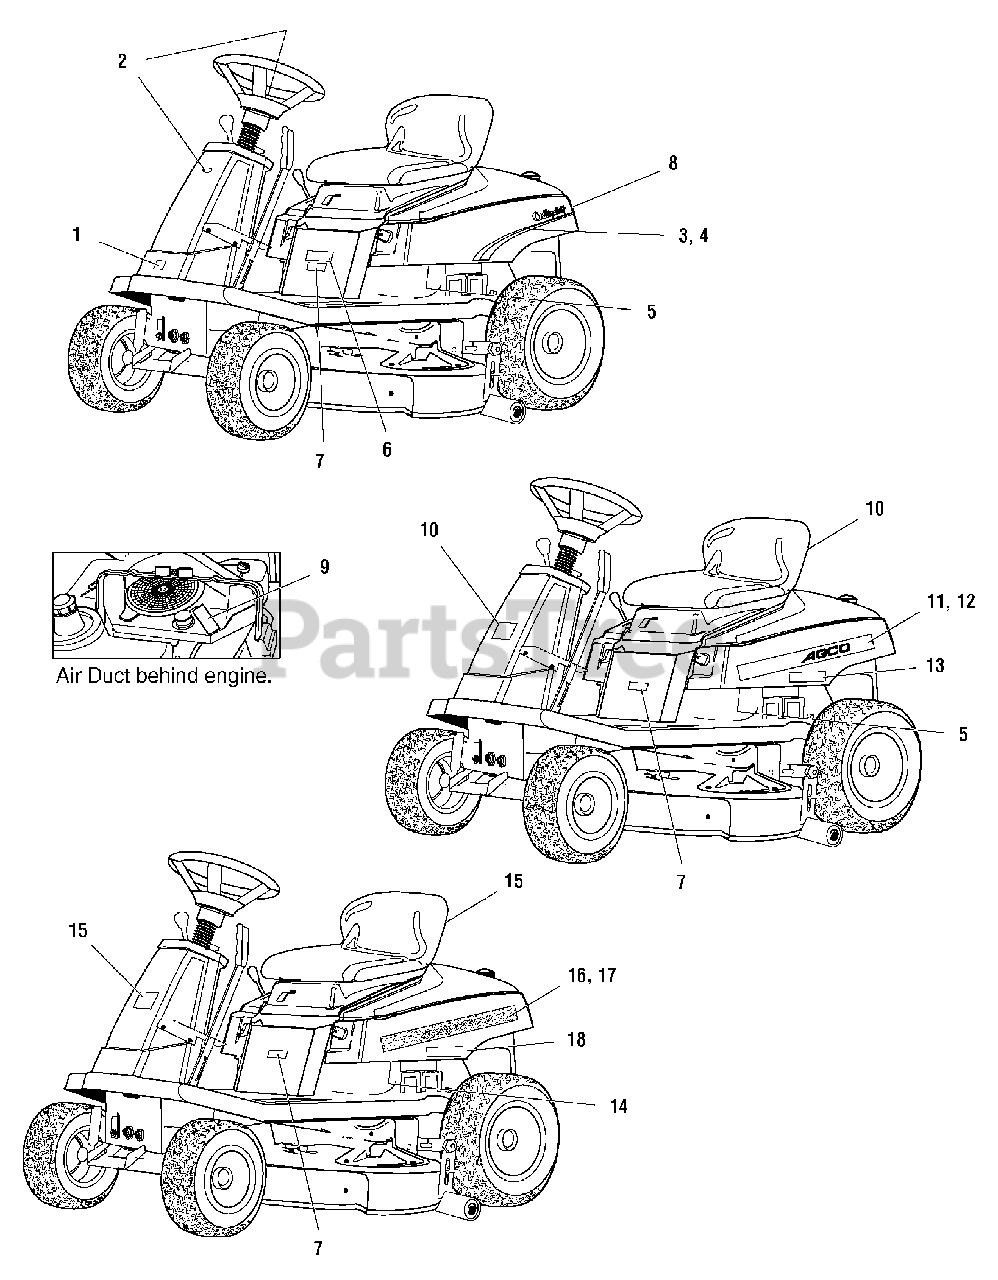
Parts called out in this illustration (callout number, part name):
1	DECAL, CE, (Export Only)
2	DECAL, Icon, Simplicity
3	DECAL, Seat Deck, LH
4	DECAL, Seat Deck, RH
5	DECAL, Touch-up Paint, Deep Orange & Charcoal Gray
6	DECAL, "CORONET"
7	DECAL, 13 HP
7	DECAL, 13.5 HP
7	DECAL, 16 HP
8	DECAL, Simplicity
9	DECAL, Briggs & Stratton, 13 HP, INTEK
10	DECAL, Logo, AGCO
11	DECAL, Seat Deck AGCO, LH
12	DECAL, Seat Deck AGCO, RH
13	DECAL, Model, 413H
14	DECAL, Touch-up Pain, Red & Gray
15	DECAL, Logo, Massey Ferguson
16	DECAL, Seat Deck, LH
17	DECAL, Seat Deck, RH
18	DECAL, Model, 2413
